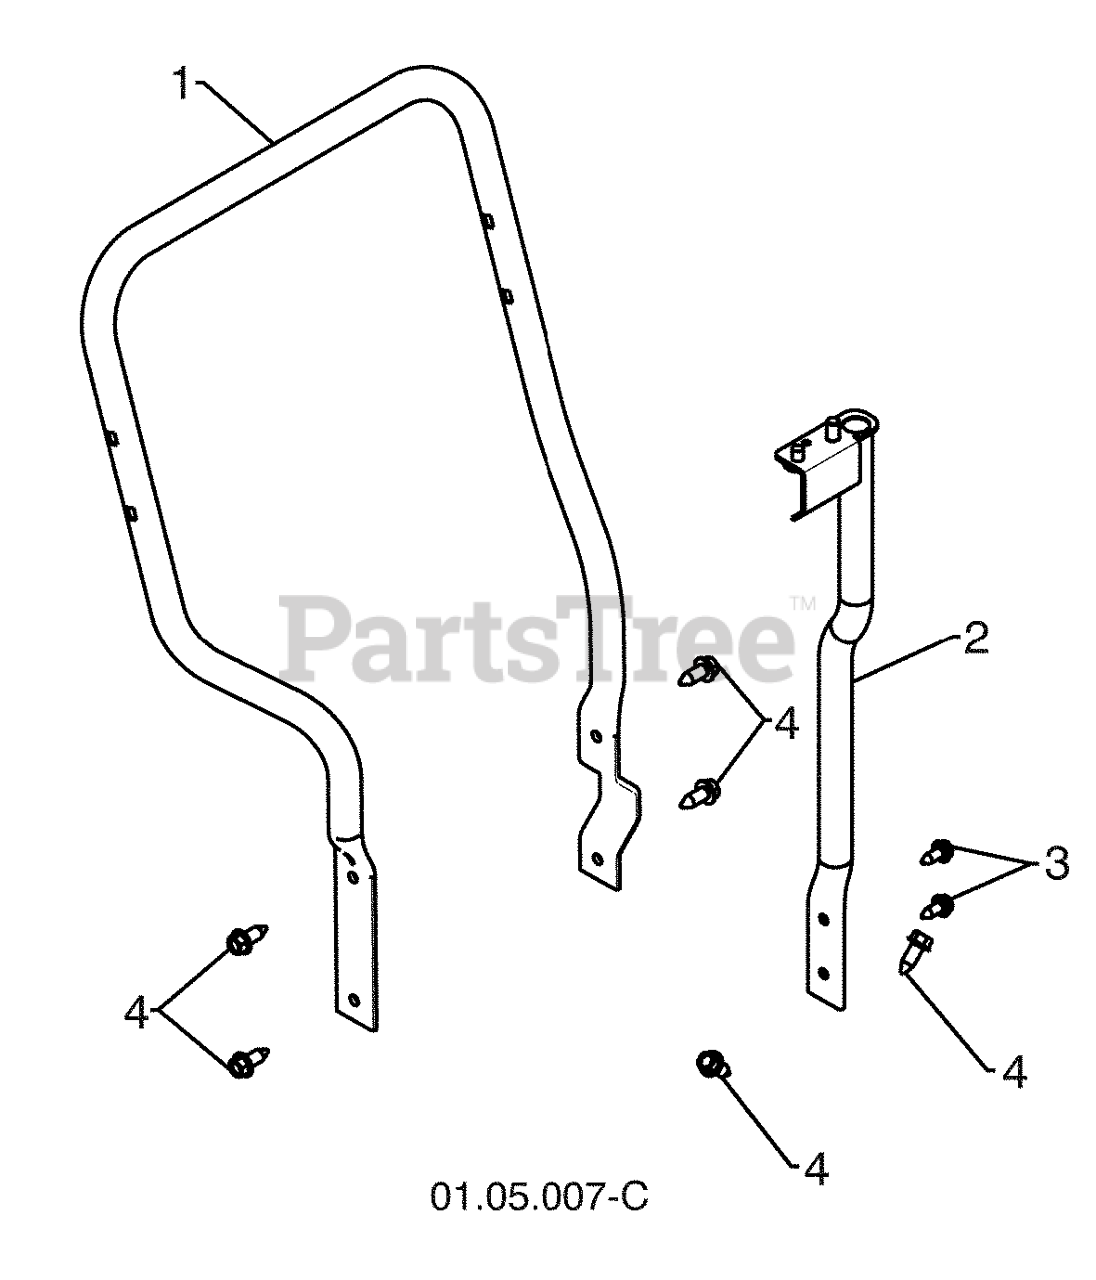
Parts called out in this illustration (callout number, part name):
1	TUBE.LOWER.HANDLE.SNOW.GRAY
2	SUPPORT.WELDMENT.ROTATOR.
3	BOLT.HEX.HD.WASHER.5/16-18X.75
4	SCREW 3/8-16X1
